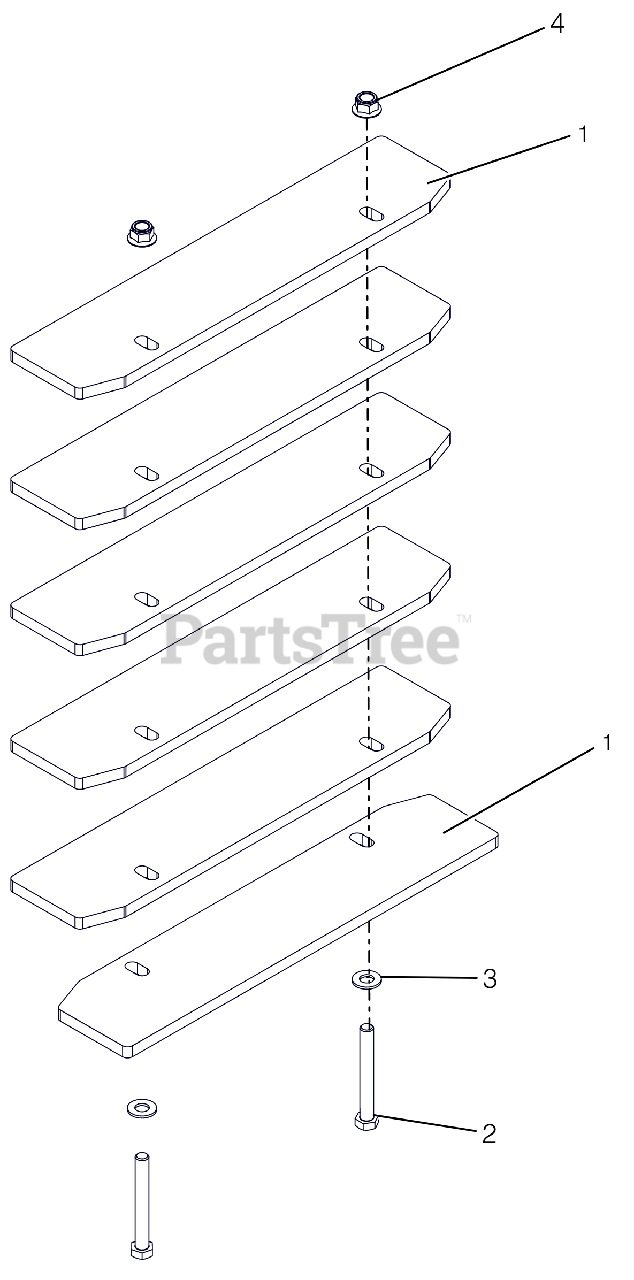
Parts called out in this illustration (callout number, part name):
1	PLATE, COUNTER WEIGHT
2	@BLT-HEX .50-13X4.00 GR5 YWZC
3	@WSHR-FL-STL.531X1.06X.095YWZC
4	@NUT-LK-NYL-FLG .50-13 YWZC
